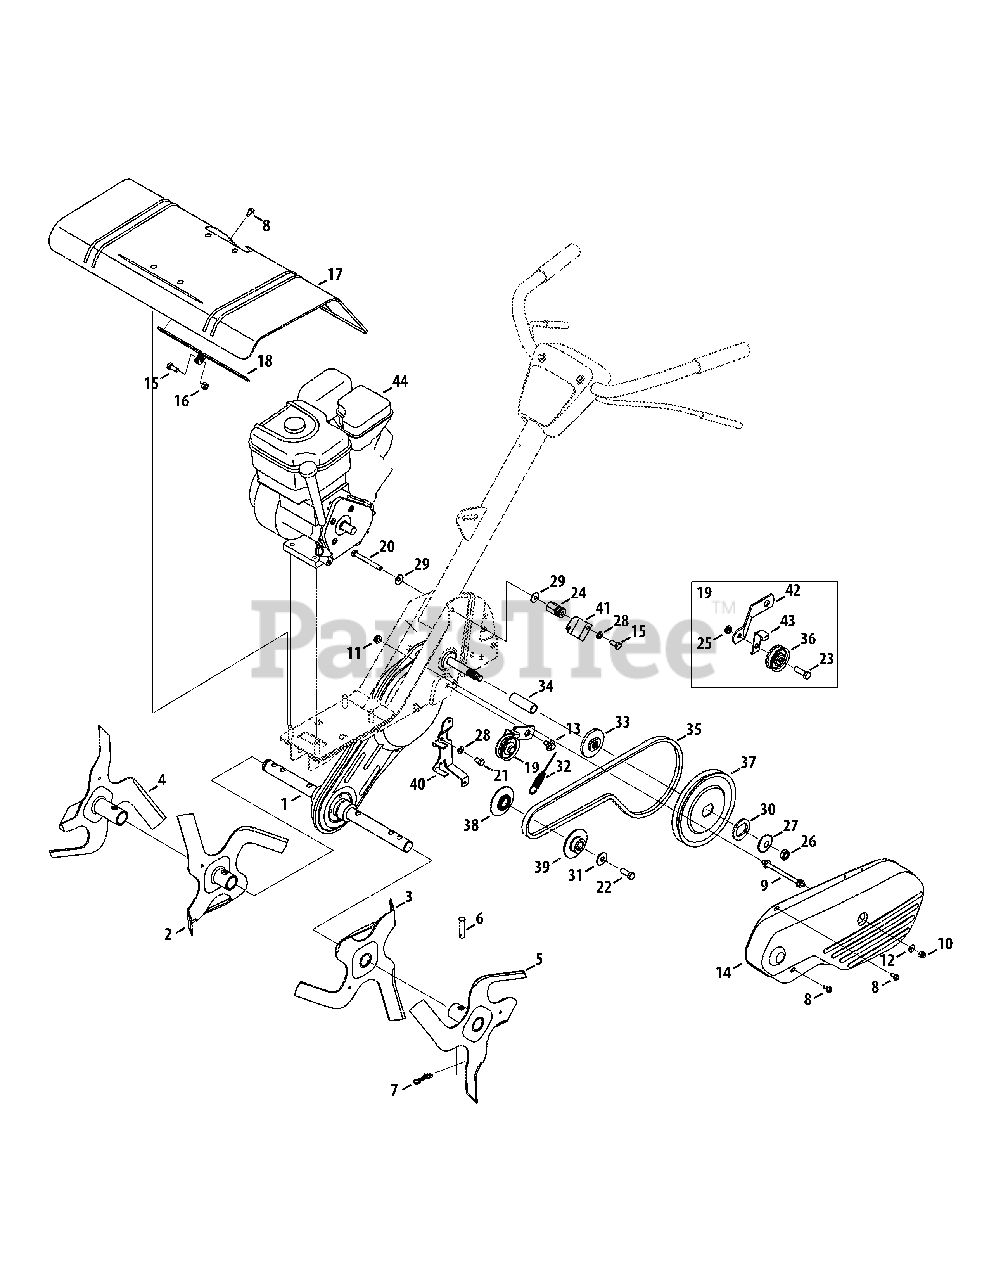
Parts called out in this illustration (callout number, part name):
1	Chain Case Assembly
2	Inner Tine Assembly, RH
3	Inner Tine Assembly, LH
4	Outer Tine Assembly, RH
5	Outer Tine Assembly, LH
6	Clevis Pin, .375 x 1.75
7	Bow Tie Cotter Pin
8	Screw, 1/4-20 x 0.500
9	Bolt, Belt Cover
10	Nut, 1/4-28, Lock
11	Nut, 5/16-18, Flange Lock
12	Flat Washer, .271 x .630 x .065
13	Shoulder Screw, .560 x .165 5/16-18
14	Belt Cover
15	Hex Head Screw, 5/16-18 x .75
16	Nut, 5/16-18, Flange Lock
17	Tine Shield
18	Bracket, Tine Shield
19	Idler Bracket Assembly
20	Hex Head Screw, 5/16-18 x 3.00
21	Hex Head Screw, 5/16-24 x .625
22	Hex Head Screw, 3/8-24 x 1.00
23	Hex Head Screw, 3/8-16 x 1.25
24	Hex Nut, 5/16-18
25	Jamlock Nut, 3/8-16
26	Nut, 1/2-20, Jam
27	Washer, .531 x 1.62 x .045
28	Lock Washer, 5/16
29	Bell Washer, .340 x .872 x .060
30	Flat Washer, 1.26 x 1.87 x .150
31	Bell Washer, .396 x 1.140 x .095
32	Forward Clutch Cable
33	Pulley Adaptor
34	Spacer, .64 ID x 2.4
35	Belt, 4L x 41.9 LG
36	Pulley 1.88 OD
37	Pulley 6.00 OD
38	Inner Engine Pulley
39	Outer Engine Pulley
40	Belt Keeper Bracket
41	Cable Guide Bracket
42	Idler Bracket
43	Belt Keeper
44	Replacement Engine 12T102-0937-F8
